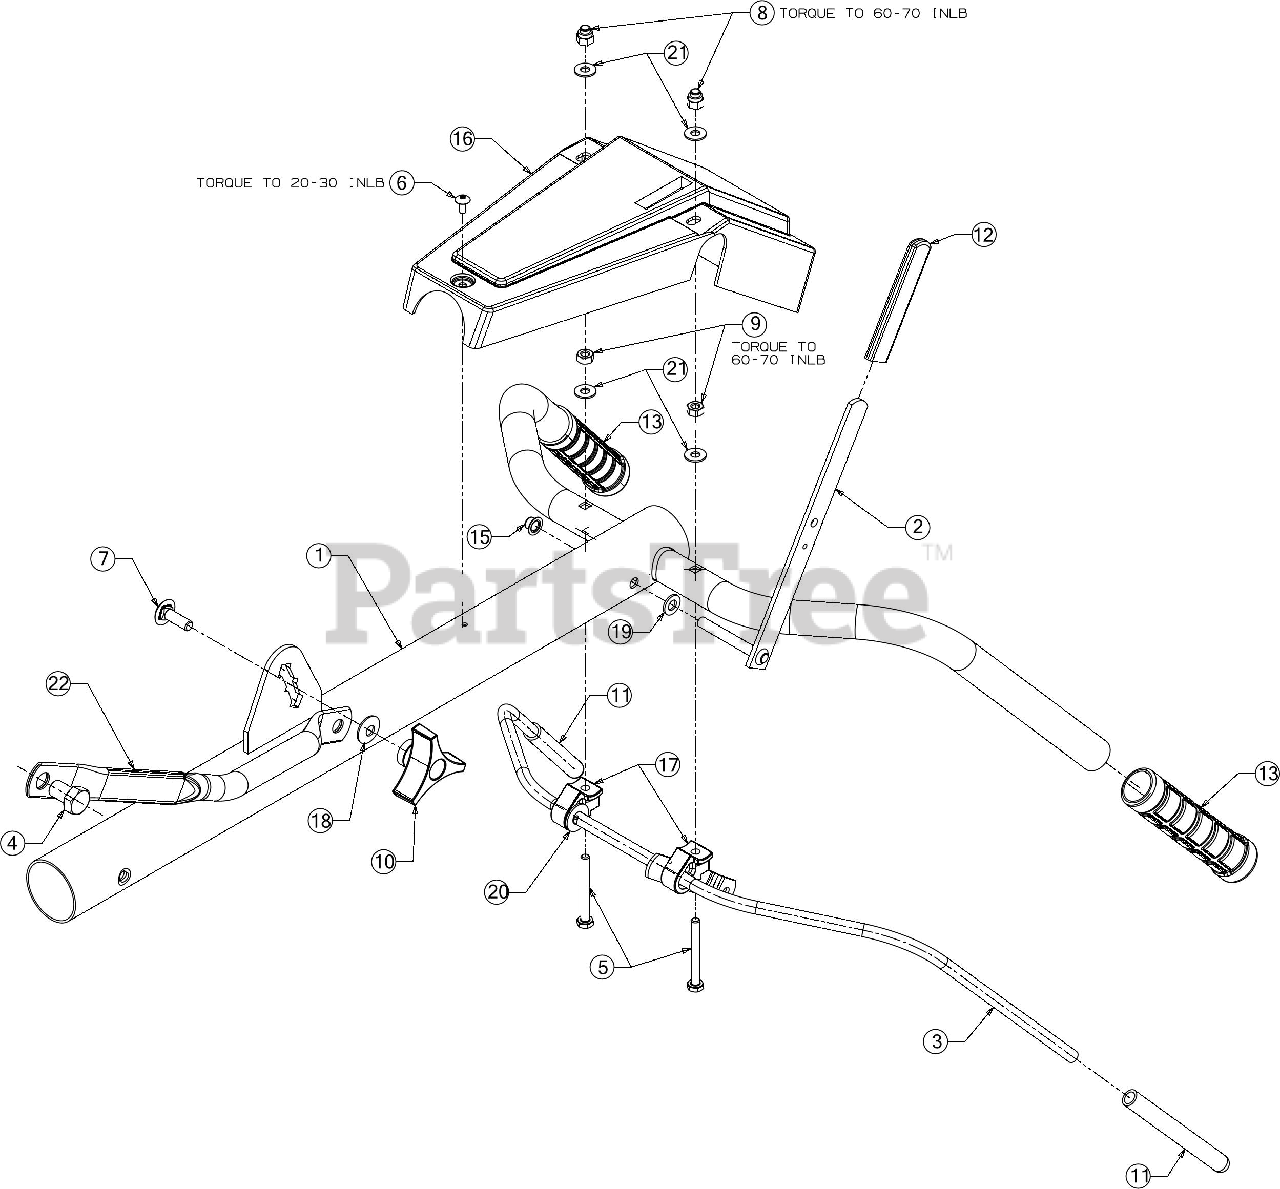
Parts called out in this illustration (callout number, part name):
1	HANDLE ASSEMBLY
2	REVERSE HANDLE ASSEMBLY
3	CLUTCH HANDLE ASSEMBLY
4	BOLT 1/2-20 X .75 GR5
5	SCREW 1/4-20 X 2.25 GR5
6	SCREW #10-16 X .500
7	SCREW 5/16-18 X 1.00
8	HEX ACORN NUT
10	HANDLE KNOB
11	CLUTCH GRIP
12	REVERSE LEVER GRIP
13	GRIP-REVERSE LEVER
15	SPEED NUT
16	HANDLE COVER PANE
17	HANDLE CLUTCH HOLDER
18	BELL WASHER .337 X.867 X .057
19	FLAT WASHER
20	FLAT WASHER
21	FLAT WASHER .271:.630:.065
